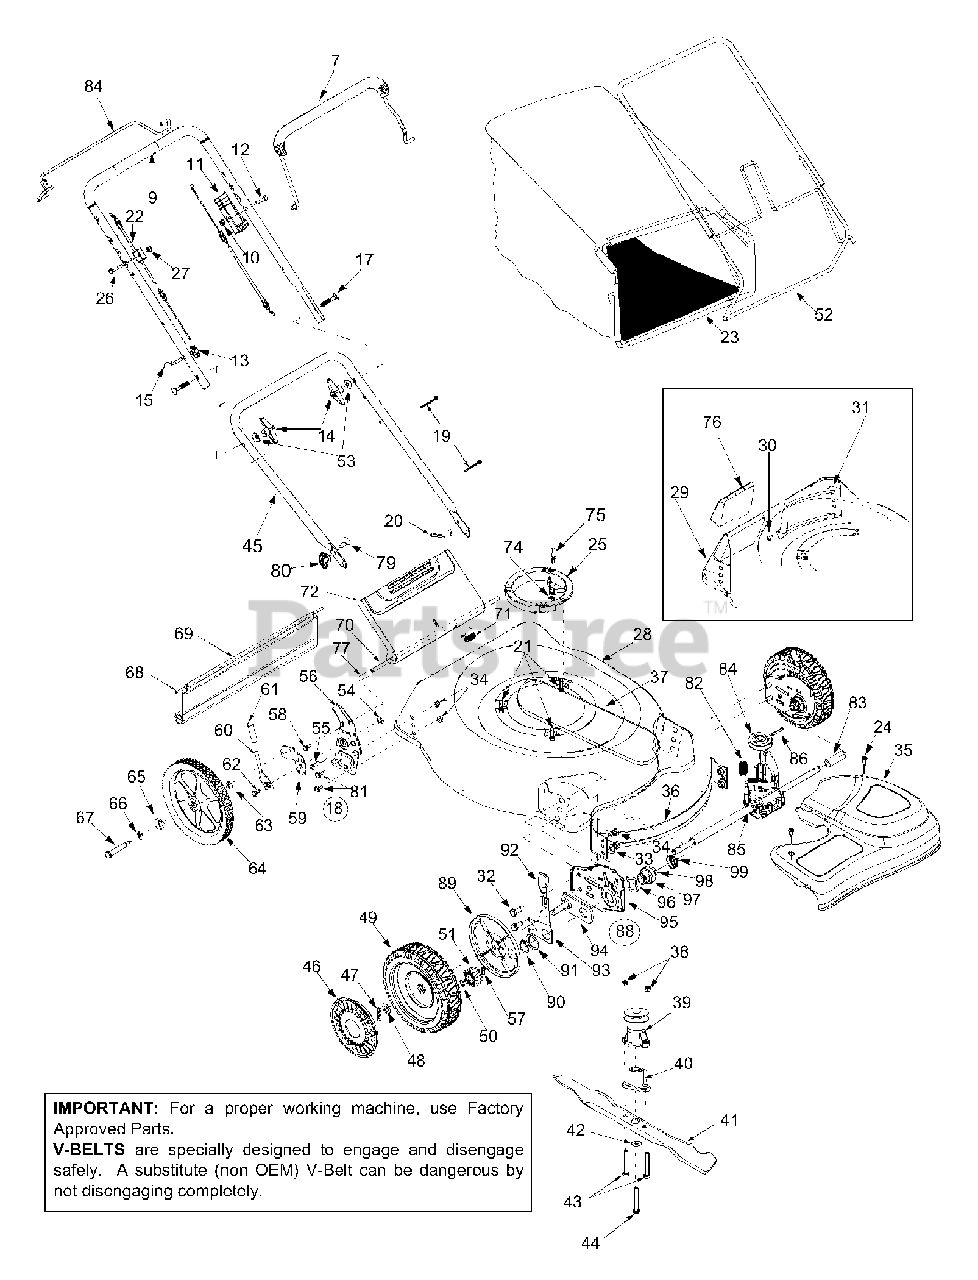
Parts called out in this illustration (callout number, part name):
10	Hex Lock Nut, 1/4-20
11	Throttle Housing
12	Oval C-Sunk Screw 1/4-20 x 1.31
13	Handle Knob
14	Handle Knob
15	Eye Bolt
17	Carriage Bolt 5/16-18 x 2.0
18	RH Bracket Ass'y
19	Cable Tie
20	Cotter Pin
21	Self-Tapping Screw
22	Drive Cable
23	Grassbag Assembly (Half Sail)
24	Shoulder Screw # 12 -24
25	Engine Spacer
26	Hex Bolt 1/4-20 x 1.5
27	Lock Nut 1/4-20
30	Screw AB: 1/4-14: .625
32	Hex Screw 3/8-16 x .75
33	Bell Washer .39 x 1.13 x .062
34	Hex Nut 3/8-16
35	Transmission Cover (Yellow)
38	Hex Nut 1/4-20
39	Drive Pulley
40	Blade Adapter
41	21" Mulching Blade
42	Flat Washer .516 x 1.5 x .134
43	Hex Screw 1/4-20 x 1.50
44	Hex Screw 3/8-24 x 2.50
46	Hub Cap
47	Cotter Pin
48	Flat Washer
49	Wheel 8 x 2
50	Snap Ring
51	Gear 14T LH FWD
53	Saddle Washer
54	Hex Flange Lock Nut 3/8-16
55	Hex Scr. w/Washer 1/4-14 x .625
57	Dowel Pin
58	Pan Head Screw
59	RH Pivot Bar
60	Height Adj. Lever
61	Foam Grip
62	Shoulder Scr .500 Dia. x .434
63	Washer .401 x .870 x .063
64	Wheel, 14 x 2
65	Spring Washer .50 I.D. x 1.0 O.D.
66	Flat Washer .510 x 1.373 x .04
67	Shoulder Screw
68	Wire
69	Rear Trailing Shield
70	Pivot Rod
71	Torsion Spring
75	Screw
76	Plastic Mulching Plug
77	Spacer .375 x .50 x 1.02" Lg.
79	Carriage Bolt 1/4-20
80	Wing Nut
81	Hex Bolt 3/8-16 x 1.0"
82	Belt Tension Spring
83	Slev. Spacer RH
84	Input Pulley
85	Transmission Assembly
86	Roll Pin
88	Height Adjustment Assembly RH
89	Wheel Dust Cap
90	Snap Ring
91	Washer
92	Adjustment Knob
93	Front Lever RH
94	Pivot Plate Assembly
97	Bearing Support
98	Bearing Sleeve
99	Bearing Retainer
